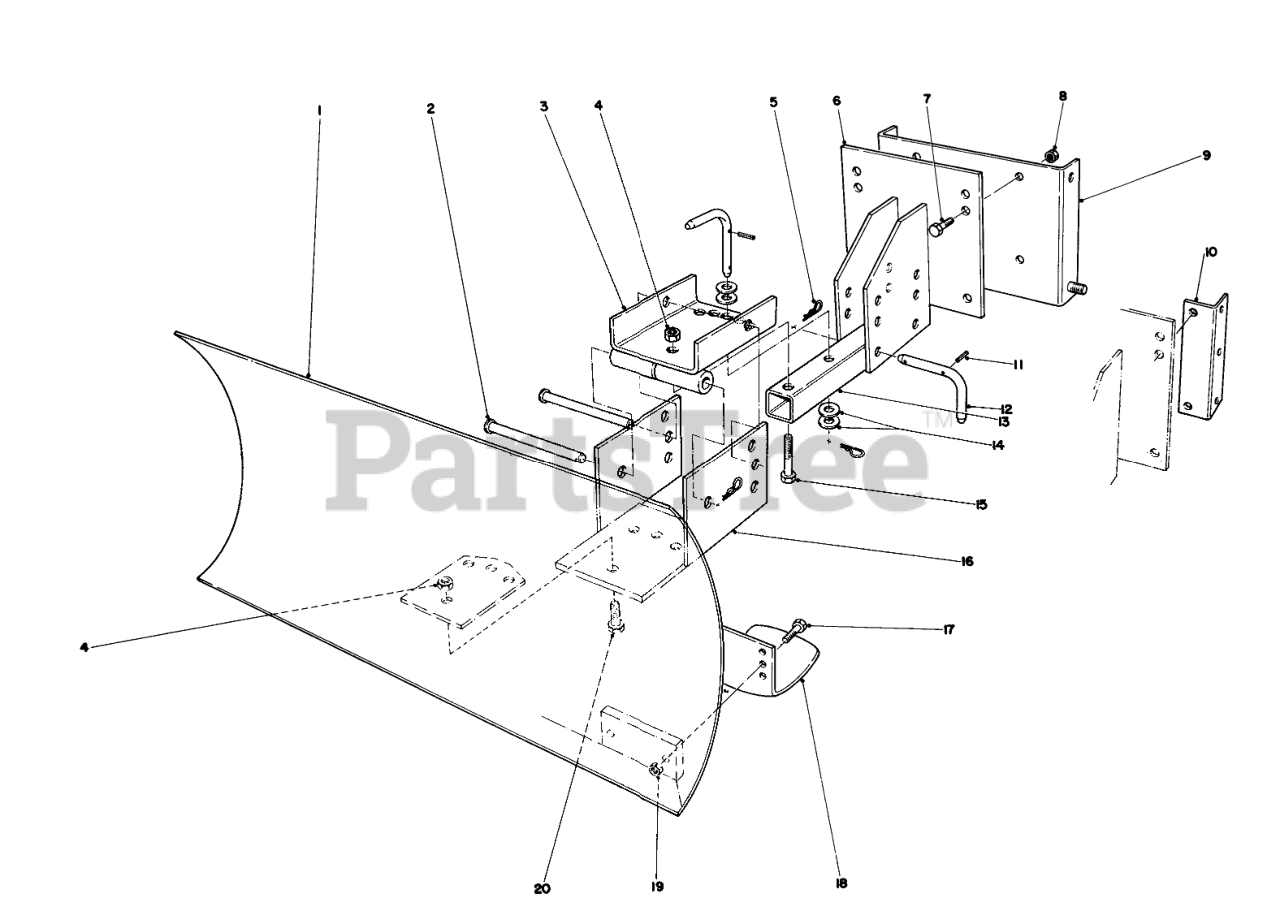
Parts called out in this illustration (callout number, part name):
1	Blade
2	PIN-CLEVIS
3	Swivel Bracket
4	1/2-13 CONELOCK NUT
5	PIN-HAIR
6	Mounting Plate
7	SCREW-HH
8	NUT-LOCK, CONE
9	Mounting Plate (Used with 826 & 1132 Units only)
10	Mounting Rail (used with 421 units only)
11	PIN-SPRING
12	Pivot Pin (Incl. Ref. #11)
13	Blade Tongue
14	WASHER-FLAT
15	SCREW-HH
16	Blade Adjustment
17	SCREW-HH
19	NUT-LOCK, CONE
20	SCREW-HH
